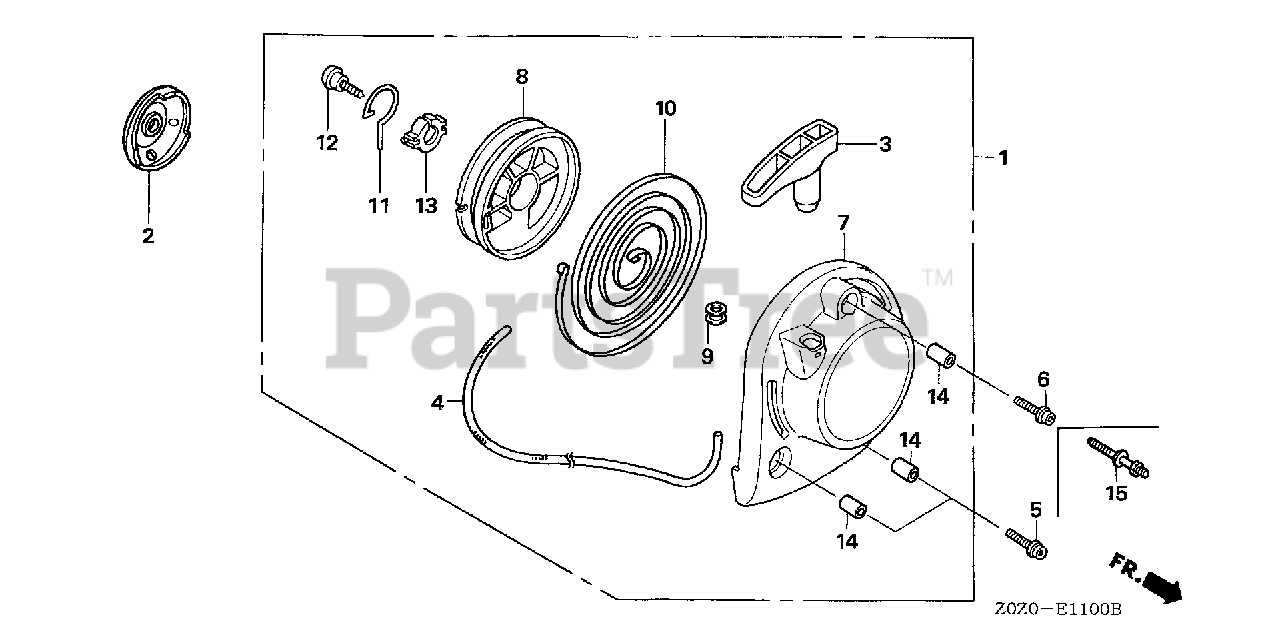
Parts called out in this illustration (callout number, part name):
1	STARTER ASSY., RECOIL (COO)(FOR U.S.A.)
2	PULLEY, RECOIL STARTER
3	KNOB, RECOIL STARTER
4	ROPE, RECOIL STARTER
5	BOLT, SOCKET (5X16)
6	BOLT, SOCKET (5X16)
7	CASE, RECOIL STARTER
8	REEL, RECOIL STARTER
9	GUIDE, ROPE
10	SPRING, RECOIL STARTER
12	SCREW, SETTING
14	COLLAR A, HEAD COVER
